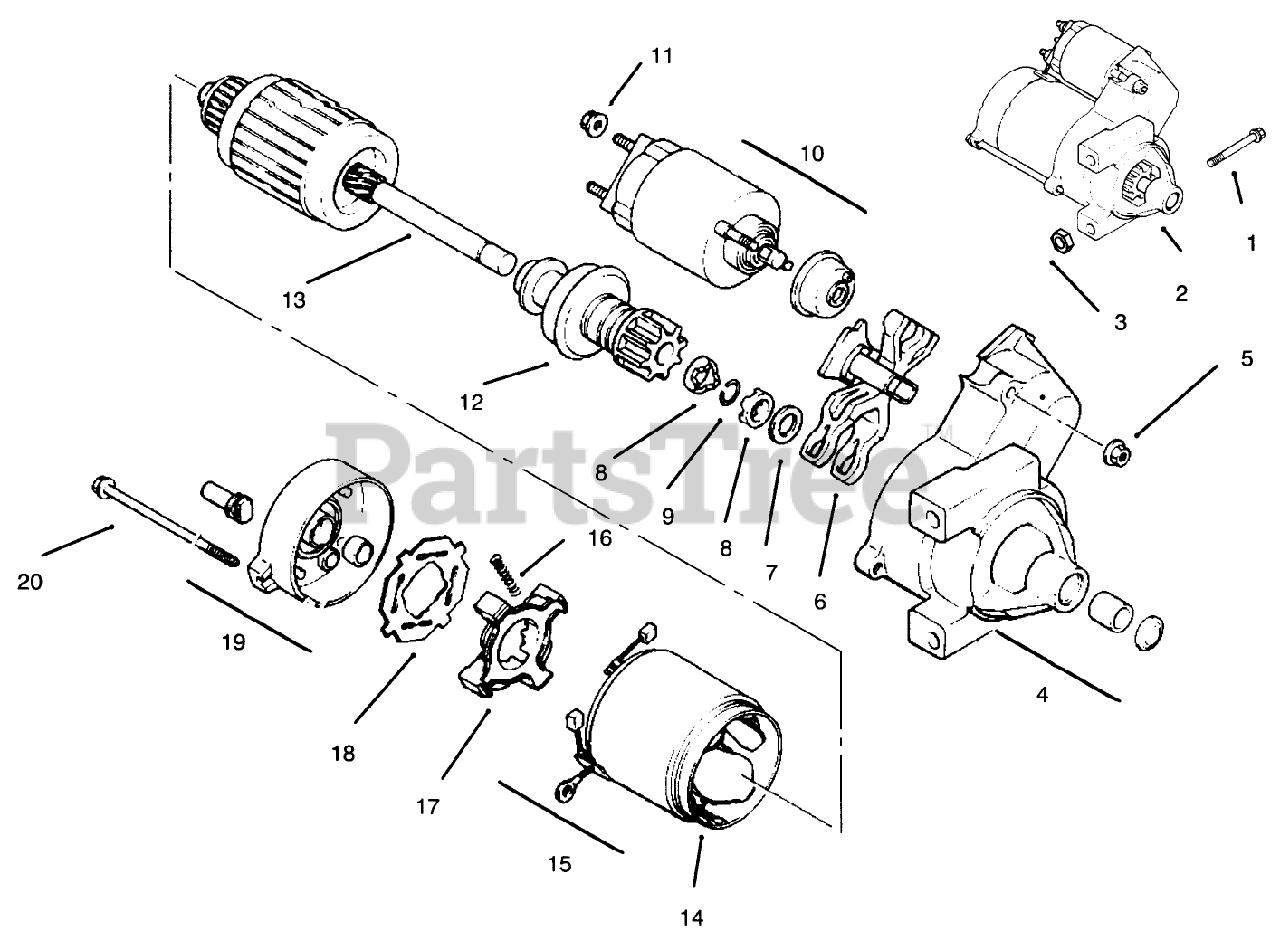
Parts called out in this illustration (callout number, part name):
2	Starter-Solenoid Shift (Incl. Ref. #4-20)
4	Cap-Drive End
5	Nut
6	Lever Starter Drive
7	Washer
8	Nut
9	Ring-Retainer
10	Solenoid
11	Nut
12	Drive Pinion
13	Armature
14	Frame
15	Kit-Brush (Incl. Ref. #16)
16	Spring Brush
17	Holder-Brush
18	Insulator
19	Cap-Commutator End
20	Bolt
